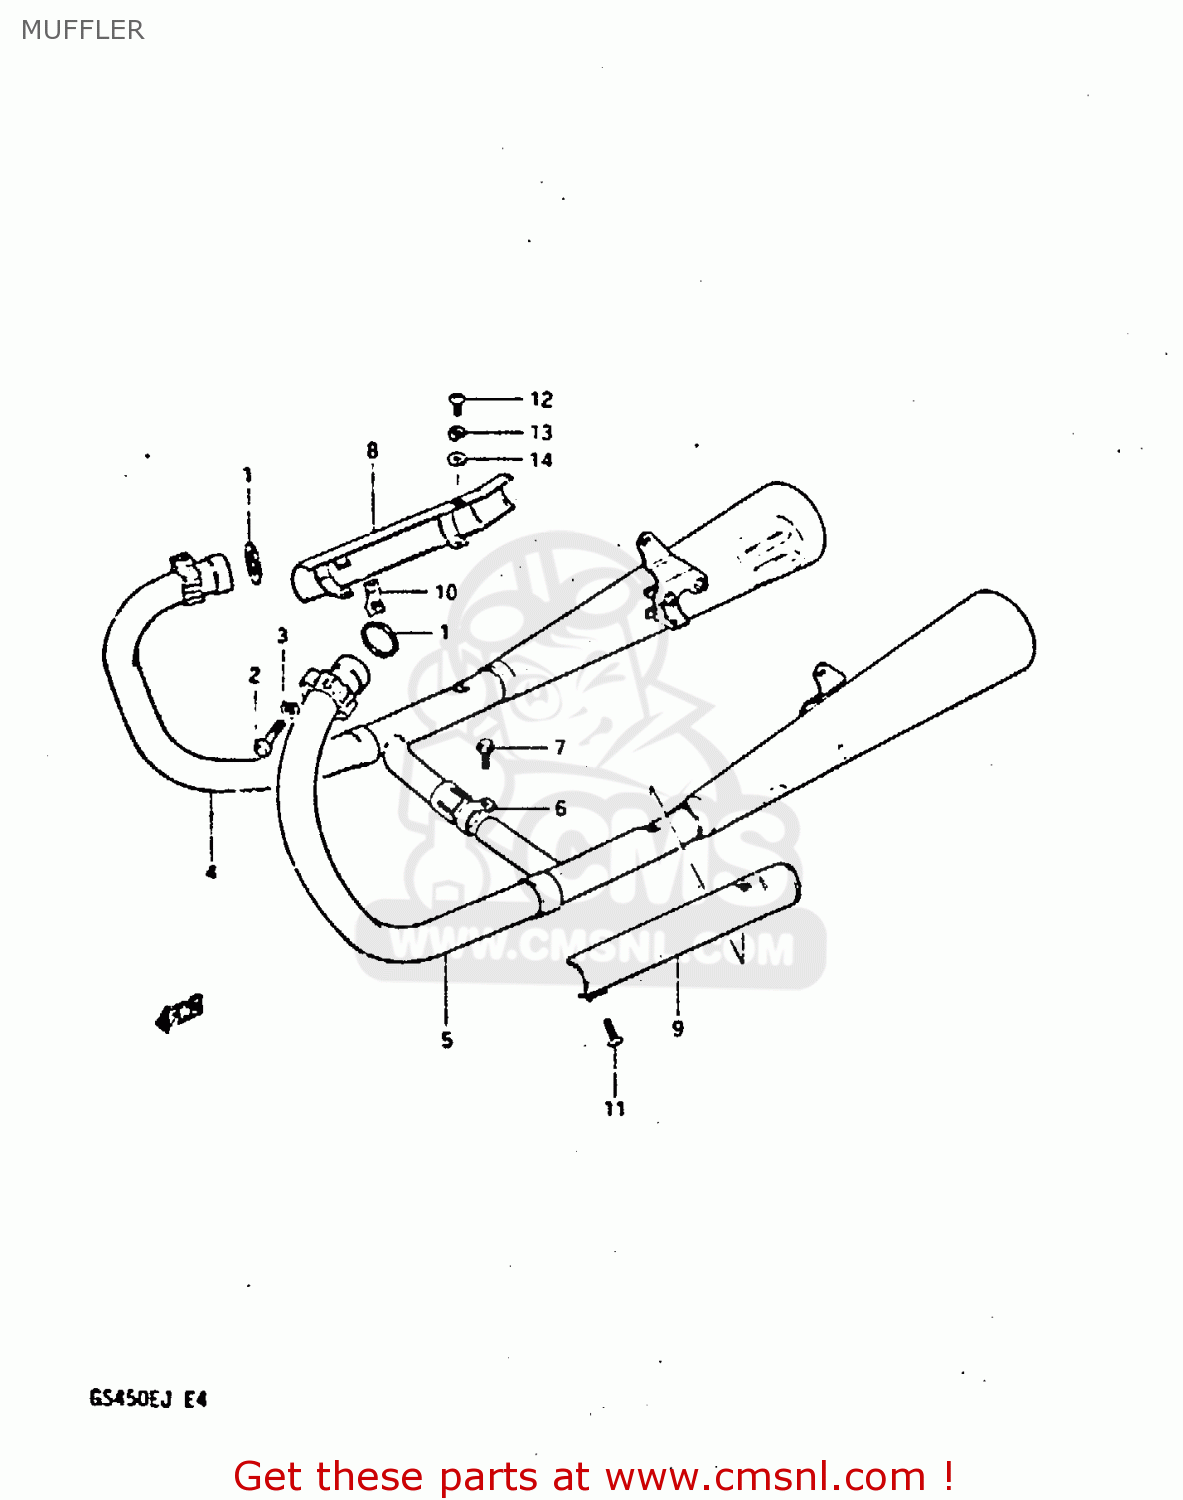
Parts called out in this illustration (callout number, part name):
1	GASKET,EXHAUST PIPE (NAS)
2	BOLT 8X40
3	LOCK WASHER
4	MUFFLER ASSY,R
5	MUFFLER ASSY,L
6	CLAMP
7	BOLT
8	COVER,MUFFLER
9	COVER,MUFFLER
10	CLAMP,MUFFLER COVER
11	SCREW
12	SCREW
13	WASHER,LOCK
14	WASHER
